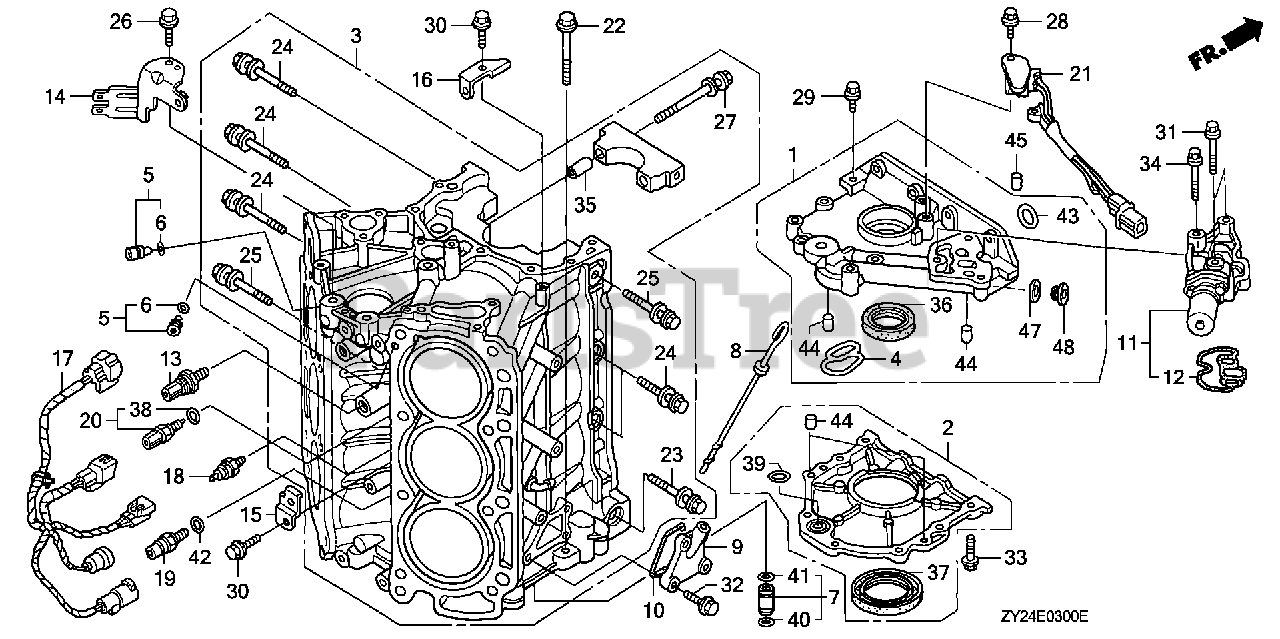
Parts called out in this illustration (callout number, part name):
1	COVER ASSY., CRANKCASE (UPPER) *NH8* (DARK GRAY)
2	CASE ASSY., OIL SEAL
3	BLOCK ASSY., CYLINDER *NH8* (DARK GRAY)
4	GASKET, OIL HOLE
5	ORIFICE ASSY., OIL CONTROL
6	O-RING (8.8X2.4)
7	JOINT ASSY., OIL PIPE
8	DIPSTICK, OIL
9	COVER, OIL LEVEL GAUGE *NH8* (DARK GRAY)
10	GASKET, OIL LEVEL GAUGE
11	VALVE ASSY., SPOOL *NH8* (DARK GRAY)
12	FILTER ASSY., SPOOL VALVE
13	SENSOR ASSY., KNOCK
14	BRACKET, CONNECTOR D
15	BRACKET, CLIP B
16	BRACKET B, HARNESS CLIP
17	WIRE, SWITCH
18	SWITCH ASSY., OIL PRESSURE
19	SWITCH ASSY., OIL PRESSURE
20	SENSOR ASSY., WATER TEMPERATURE
21	SENSOR ASSY., CRANK
22	BOLT, FLANGE (12X95)
23	BOLT-WASHER (10X109)
24	BOLT-WASHER (10X60)
25	BOLT-WASHER (10X80)
26	BOLT, FLANGE (6X14) (CT200)
27	BOLT-WASHER (11X105)
28	BOLT, FLANGE (6X16)
29	BOLT, FLANGE (6X35)
30	BOLT, FLANGE (6X14)
31	BOLT, FLANGE (8X50)
32	BOLT, FLANGE (6X18)
33	BOLT, FLANGE (6X22)
34	BOLT, FLANGE (8X75)
35	PIN, DOWEL (13X37)
36	OIL SEAL (41X66X8)
37	OIL SEAL (80X98X10) (NOK)
38	O-RING (9.5X1.9)
39	O-RING (26.2X2.4) (YAMADA SOMBOON)
40	O-RING (18.3X3.5)
41	O-RING (16.3X3.5)
42	O-RING (13X1.5) (ARAI)
43	O-RING (25X2.4) (NOK)
44	PIN, DOWEL (6X10)
45	PIN, DOWEL (5X8)
47	WASHER, SEALING (22MM)
48	BOLT, SEALING (22MM)
